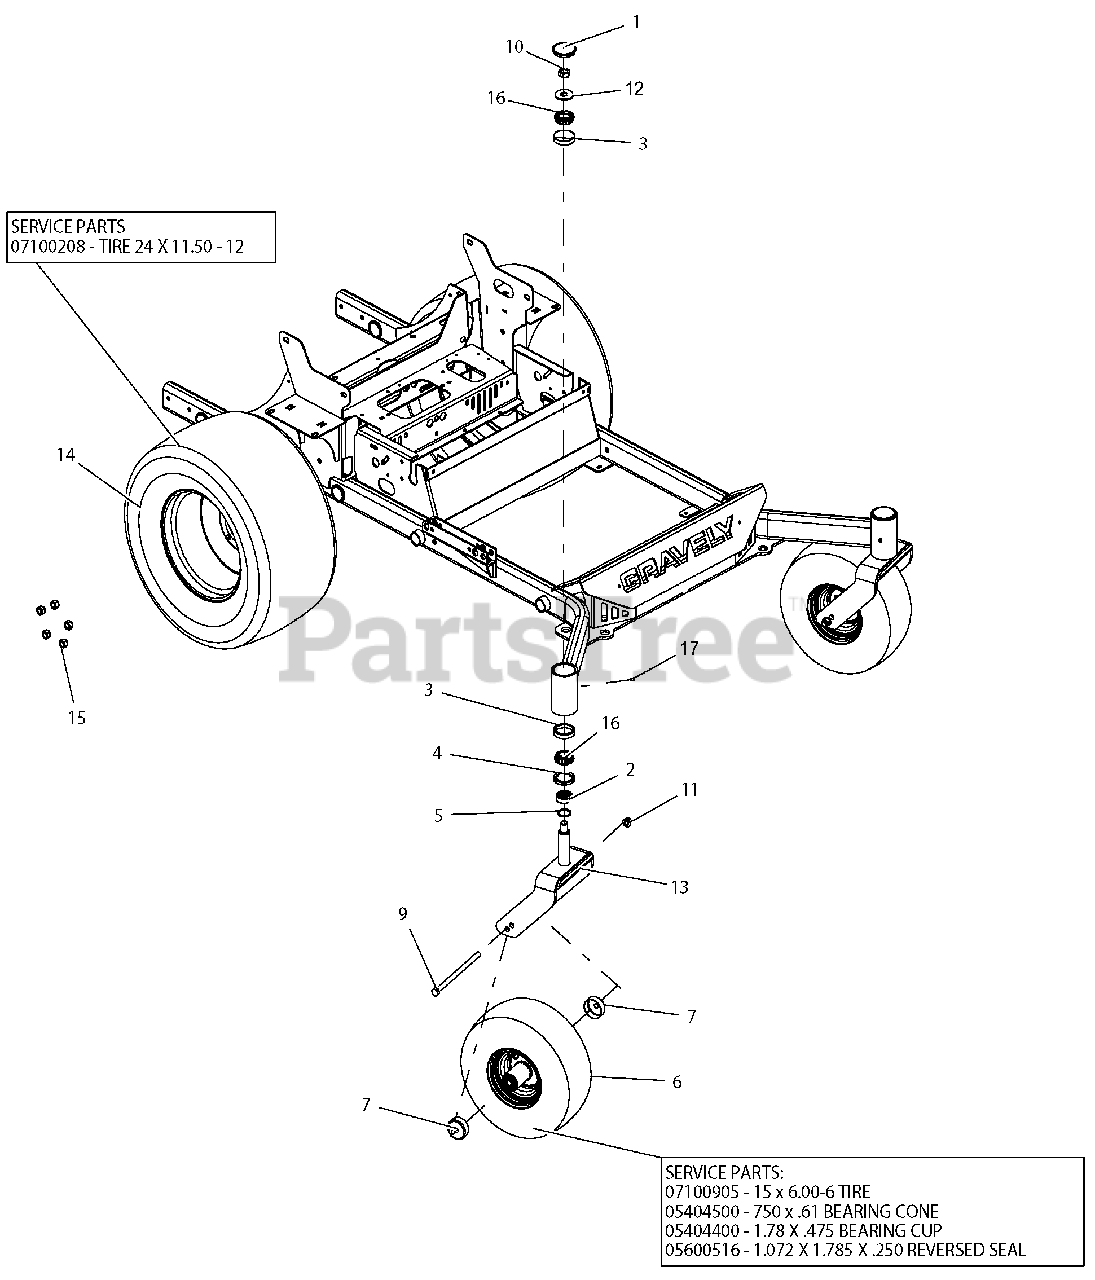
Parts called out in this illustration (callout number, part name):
1	CAP, DUST
2	SPCR, FRONT CASTER FORK
3	BRG, CUP 2.328 X .465
4	SEAL, OIL 1.75 X 2.332 X .312
5	O-RING, .139 W X 1.234 ID
6	TIRE/WHEEL, 15 X 6.00-6 SMOOTH
6	15 x 6.00-6 TIRE
6	750 x .61 BEARING CONE
6	1.78 X .475 BEARING CUP
6	1.072 X 1.785 X .250 REVERSED SEAL
7	SHIELD, WHEEL BEARING
9	BLT-HEX .50-13X9.00 GR5 YWZC
10	@NUT-LK-CTR-JAM .75-16 YWZC
11	NUT, LK-TOP-FLG .50-13 YWZC
12	WSHR-FL-STL.812X2.00X.148YWZC
13	WMT, CASTER FORK - RED
14	TIRE/WHEEL, ASM 24X11.50-12
14	TIRE 24 X 11.50 - 12
15	NUT, LUG .500-13
16	BRG, CONE 1.250 X .660
17	FITTING, .250-28 FLUSH MOUNT GREASE
